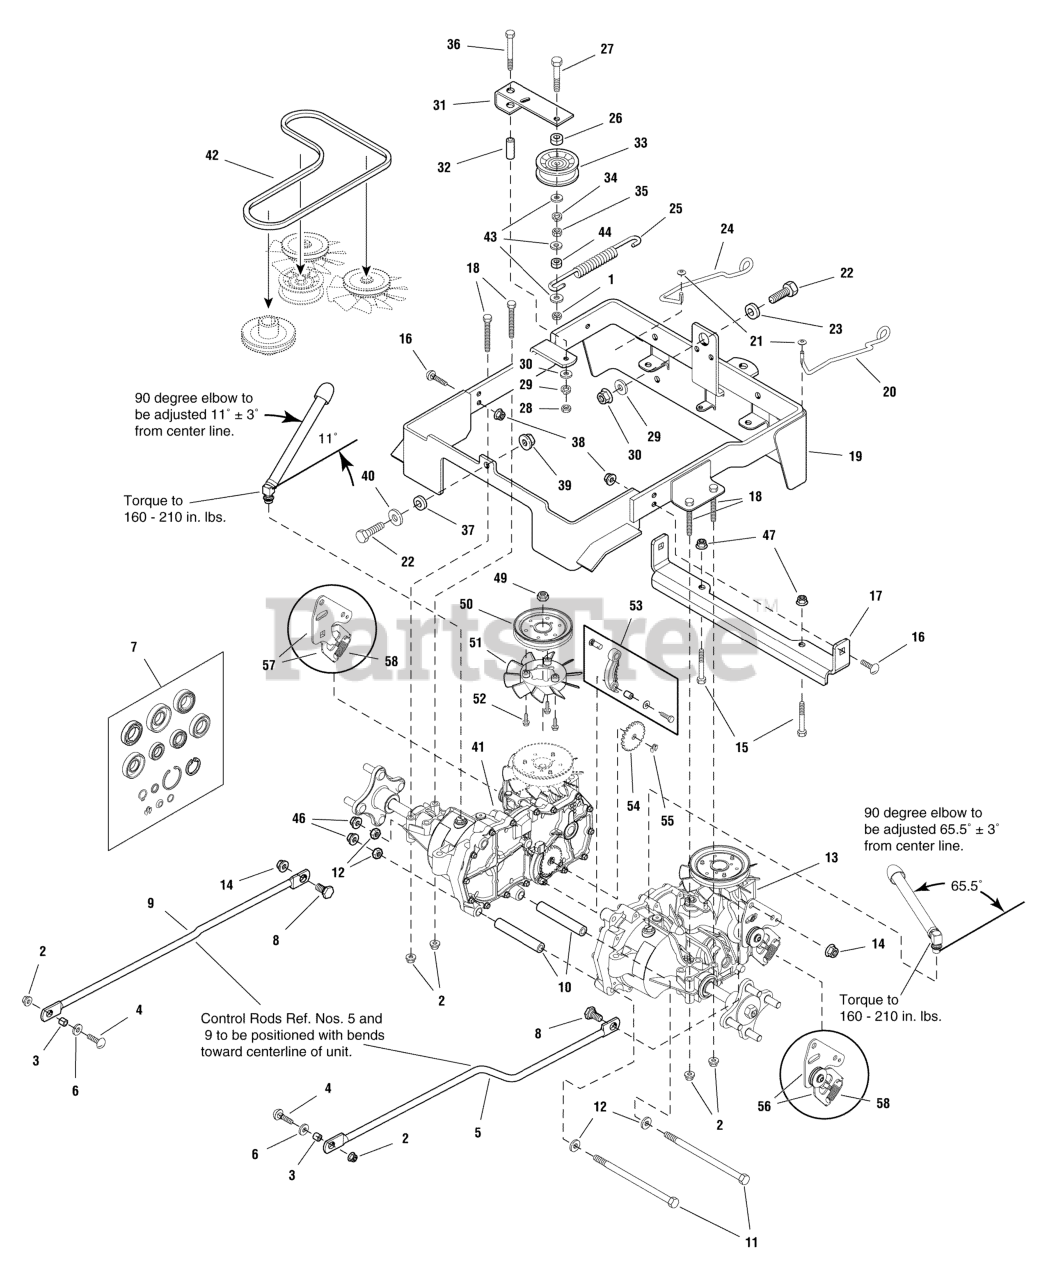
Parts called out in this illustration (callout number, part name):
1	NUT, Hex Centerlock Jam, 3/8-16
2	NUT, Hex Flange, 5/16-18 ESNA
4	BOLT, Carriage, 5/16-18 x 1 1/4
5	ROD, Control, L.H.
6	WASHER, 5/16
7	HYDRO SEAL KIT
8	BOLT, Shoulder, 7/16-14, G5
9	ROD, Control, R.H.
11	CAPSCREW, Hex Head, 7/16-14 x 8, G5
12	WASHER, 7/16
13	TRANSMISSION, Hydro Gear, L.H.
14	NUT, Hex Flange, 7/16-14, Two-Way Lock
15	SCREW, Hex Washer Head Taptite, 3/8-16 x 2-1/2
16	CARRIAGE BOLT, 3/8-16 x 1-1/4, G5
17	SUPPORT, Center Transmission
18	CAPSCREW, Hex Head, 5/16-18 x 2-3/4, G5
19	FRAME ASSEMBLY, Carrier Transmission
20	ROD, Actuator, R.H. E-Coat
21	CLIP, Rod End Clevis L.H.
22	CAPSCREW, Hex Head, 1/2-13 x 1-1/4, G5
24	ROD, Actuator, L.H. E-Coat
25	SPRING, Extension
26	SPACER, Powdered Metal
27	CAPSCREW, Hex Head, 3/8-16 x 2-1/4, G5
28	NUT, Hex, 5/16-18
29	LOCKWASHER, Spring 5/16
30	WASHER, 5/16
31	ARM, Idler
32	SPACER, Powdered Metal
33	PULLEY, Idler
34	LOCKWASHER, Spring, 3/8
35	NUT, Hex, 3/8-16
36	CAPSCREW, Hex Head, 5/16-18 x 2-1/2, G5
38	NUT, Hex Flange, 3/8-16, Whiz Lock
39	NUT, Hex Flange, Two-Way Lock, 1/2-13
40	WASHER, 1/2
41	TRANSMISSION, Hydro Gear, R.H.
43	WASHER, 3/8
45	NUT, Hex, 1/2-20
46	NUT, Hex Centerlock Jam, 7/16-14
47	NUT, Hex Flange, 3/8-16, Whiz Lock
48	CLIP, Rod End Clevis R.H.
49	NUT, Hex Head Center Lock
50	PULLEY, 4.5", Transmission
51	FAN, 6", Transmission
52	CAPSCREW, Hex Head, Transmission
53	PARKING BRAKE ARM ASSEMBLY, Transmission L.H. or R.H.
54	GEAR, Parking Brake, Transmission
55	CLIP, E Transmission Parking Brake
56	ARM, Control Kit L.H.
57	ARM, Control Kit R.H.
58	SPRING, Extension
